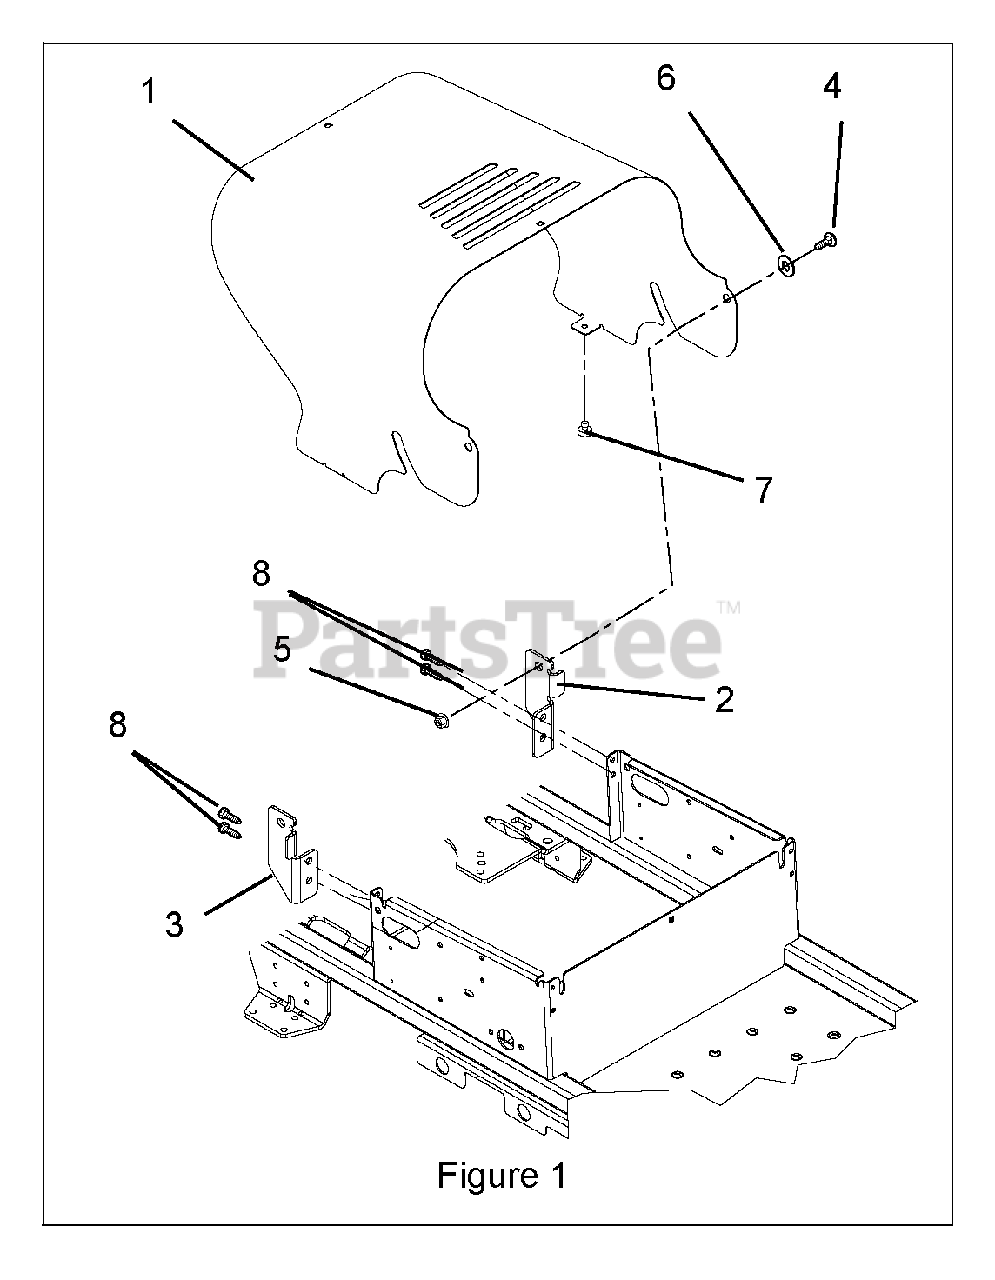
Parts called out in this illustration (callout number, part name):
1	HOOD, ZOOM (ARIENS)
2	HOOD MOUNT, LEFT
3	HOOD MOUNT, RIGHT
4	BOLT-SHLDR .375-16X.150
5	@NUT-LK-TOP-FLG .38-16 YWZC
6	WSHR-FL-NYL .518X1.000X.080
7	BUTTON BUMPER
8	@SCR-TAP .31-18X.75 HWH TR YWZ
